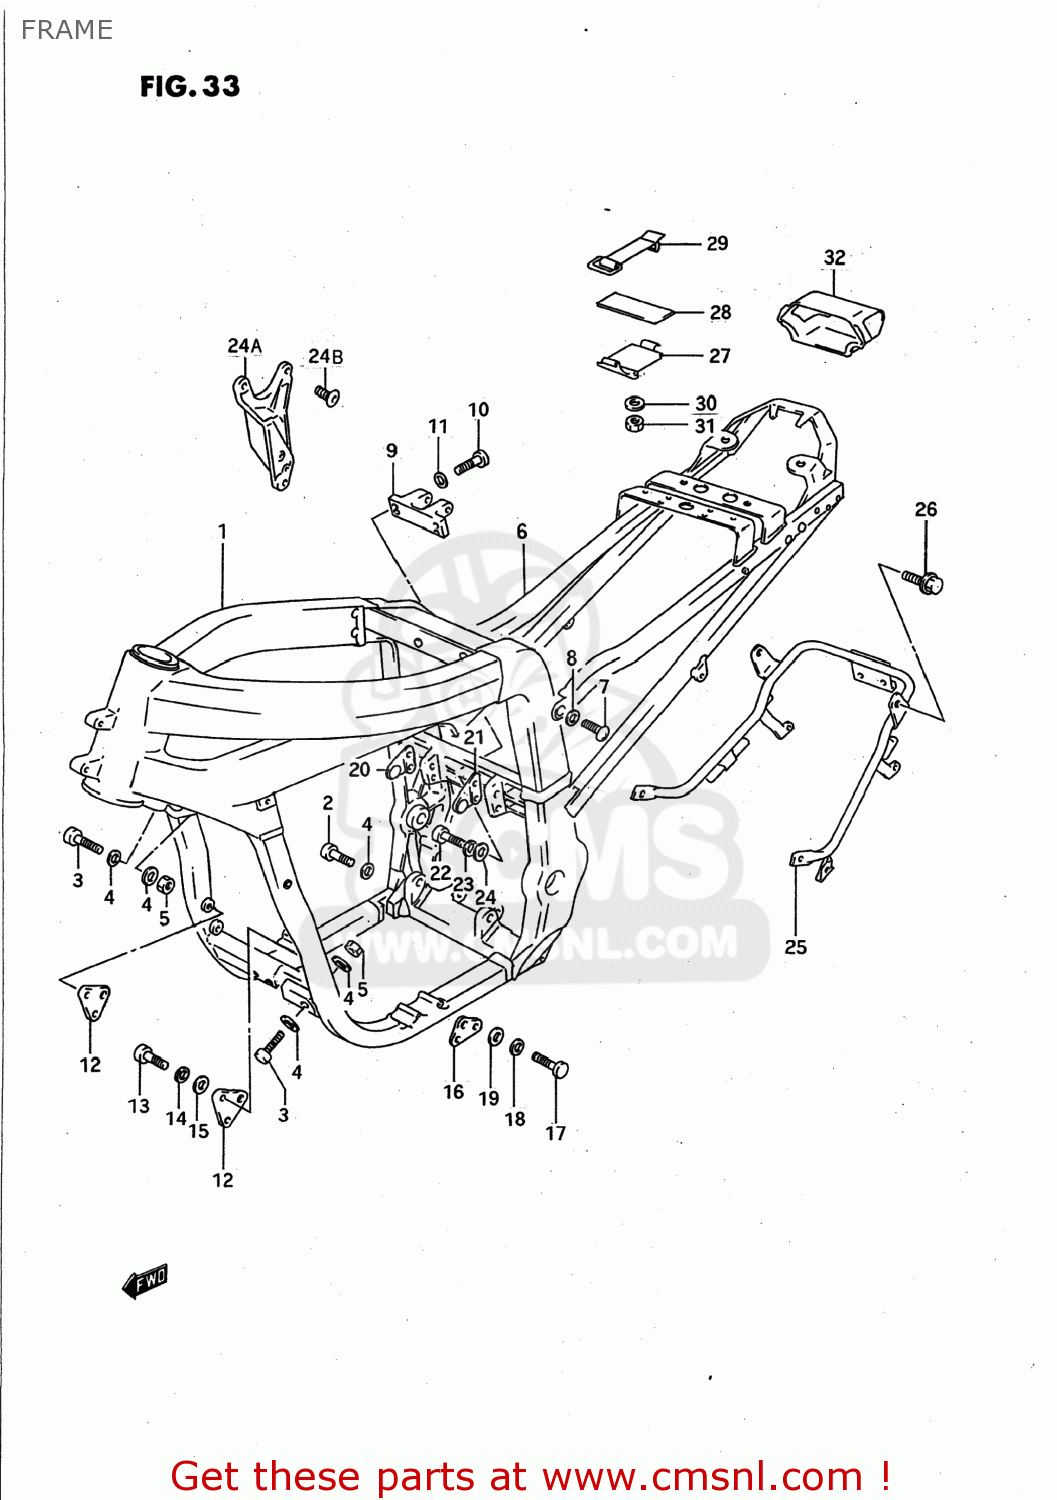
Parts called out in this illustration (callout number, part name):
1	FRAME SET
2	BOLT
3	BOLT
4	WASHER (10.1X21X2.3)
5	NUT
6	RAIL,SEAT
7	BOLT,FOOTREST BRACKET
8	WASHER
9	BRACKET,R.C.U.
10	BOLT(8X28)
11	WASHER
12	PLATE,ENG MTG NO.1
13	BOLT
14	WASHER,LOCK
15	WASHER (8.2X20X1.6)
16	PLATE,ENG MTG NO.2,R
17	BOLT
18	WASHER,LOCK
19	WASHER (8.2X20X1.6)
20	PLATE,ENGINE MOUNTING NO.3
21	PLATE,ENG MTG NO.3,L
22	BOLT(8X22)
23	WASHER,LOCK
24	WASHER (8.2X20X1.6)
24A	PLATE,ENGINE MOUNT UPR
24B	BOLT
25	GRIP COMP,REAR
26	BOLT
27	HOLDER,TOOL
28	COVER,HARNESS
29	BAND
30	WASHER
31	NUT
32	HOLDER,TOOL
